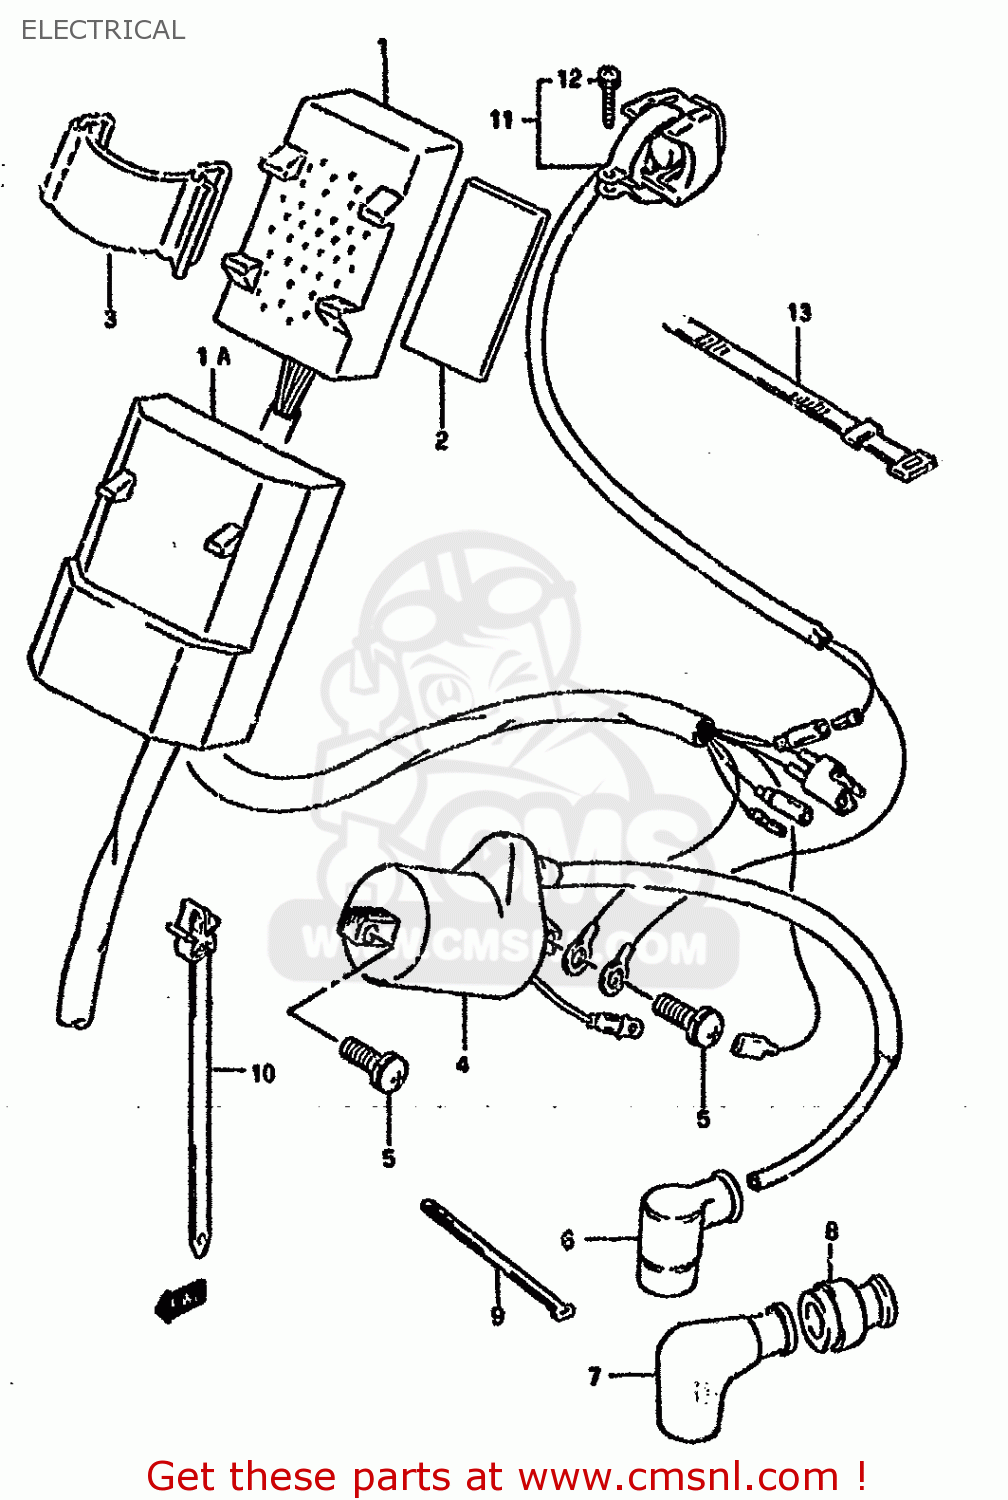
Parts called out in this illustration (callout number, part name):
1	CDI UNIT
1A	CDI UNIT
2	PROTECTOR(170X95X3.0)
3	BAND(L:65)
4	COIL ASSY,IGNITION
5	SCREW
6	CAP,SPARK PLUG
7	CAP,SPARK PLUG
8	SEAL,HIGH TENSION CORD
9	CLAMP
10	CLAMP(L:90)
11	SWITCH ASSEMBLY
12	SCREW
13	CLAMP(L:120)
